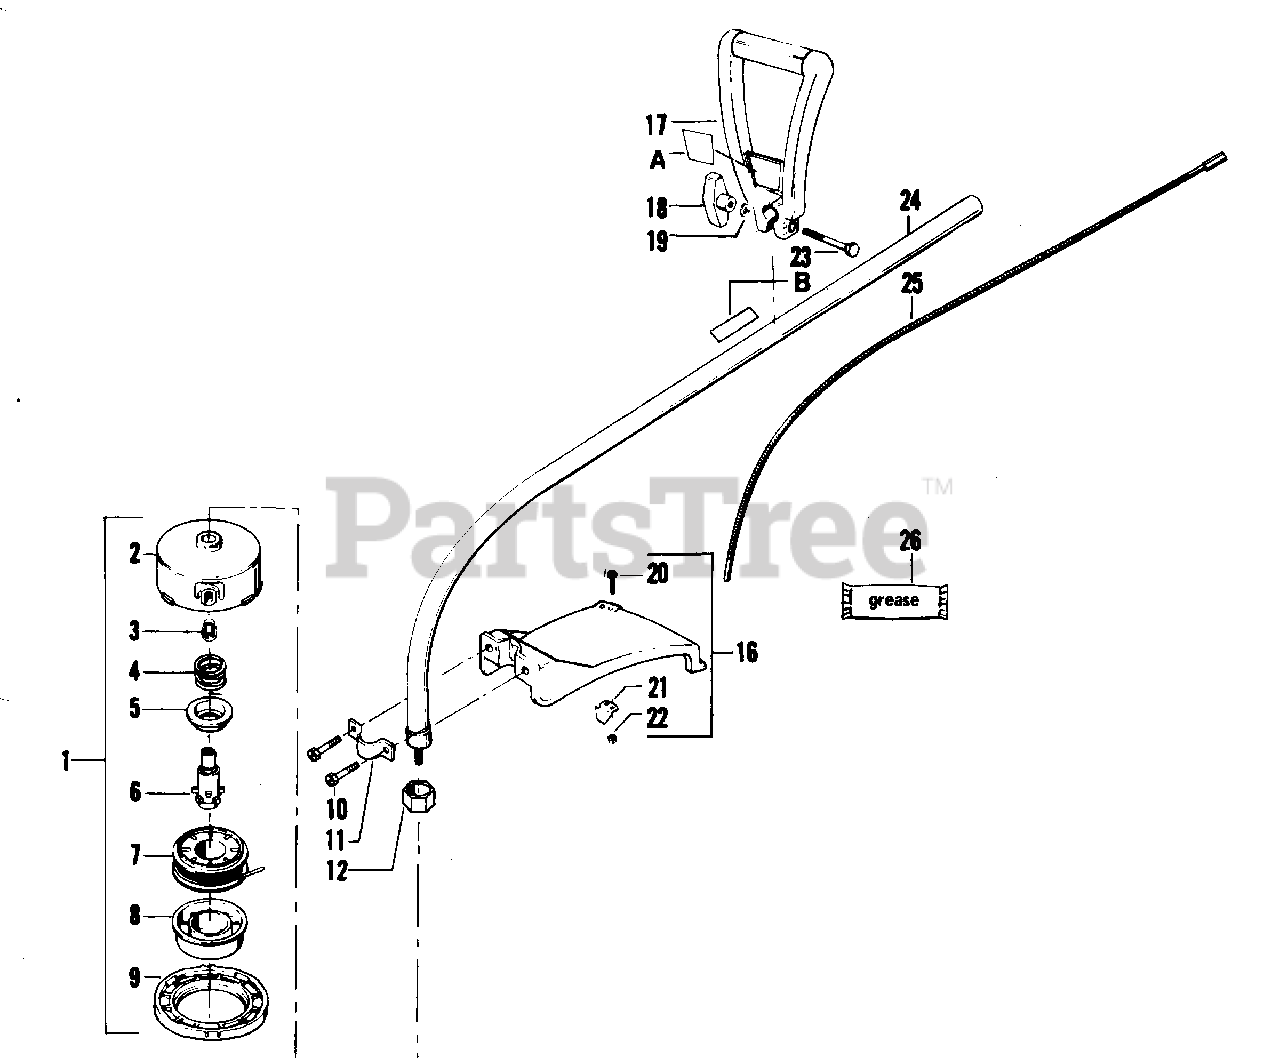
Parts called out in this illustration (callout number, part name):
1	Cutting Head Ass'y (Inc.2 - 9)
2	Hub w/Line Saver
3	Line Saver
4	Spring
5	Adaptor - Spring
6	Drive Gear
7	Spool w/Line
8	Release Button
11	Bracket - Shield
12	Dust Cup
17	Assist Handle
18	Knob - #1/4 - 20
19	Washer - #1/4 Flat
20	Screw - Line Limiter
21	Limiter - Line
22	Nut - #10 - 24 Line Limiter
23	Hex Bolt - #1/4 - 20 x 2-1/4"
24	Drive Shaft Ass'y (Inc.12)
25	Flexible Shaft Assembly
26	Flex Shaft Lube (Optional)
A	Decal - "D" Handle Warning
B	Decal - Warning
